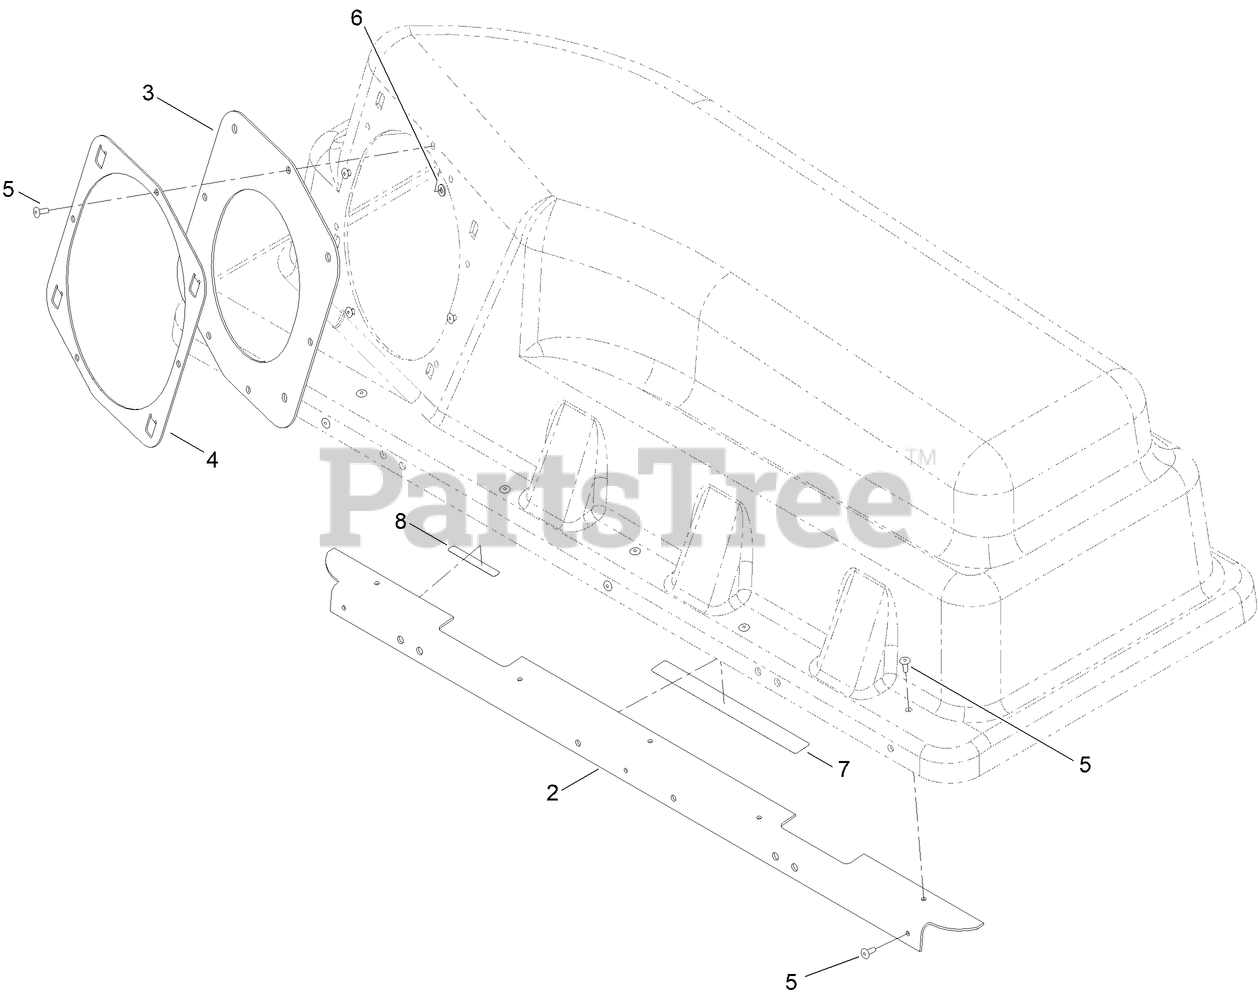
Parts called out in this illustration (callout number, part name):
2	STIFFENER-BAGGER TOP
4	RING-RETAINER
5	RIVET-BLIND
6	Washer-Plain
7	DECAL-CAUTION, BAGGER
8	DECAL-WARNING
